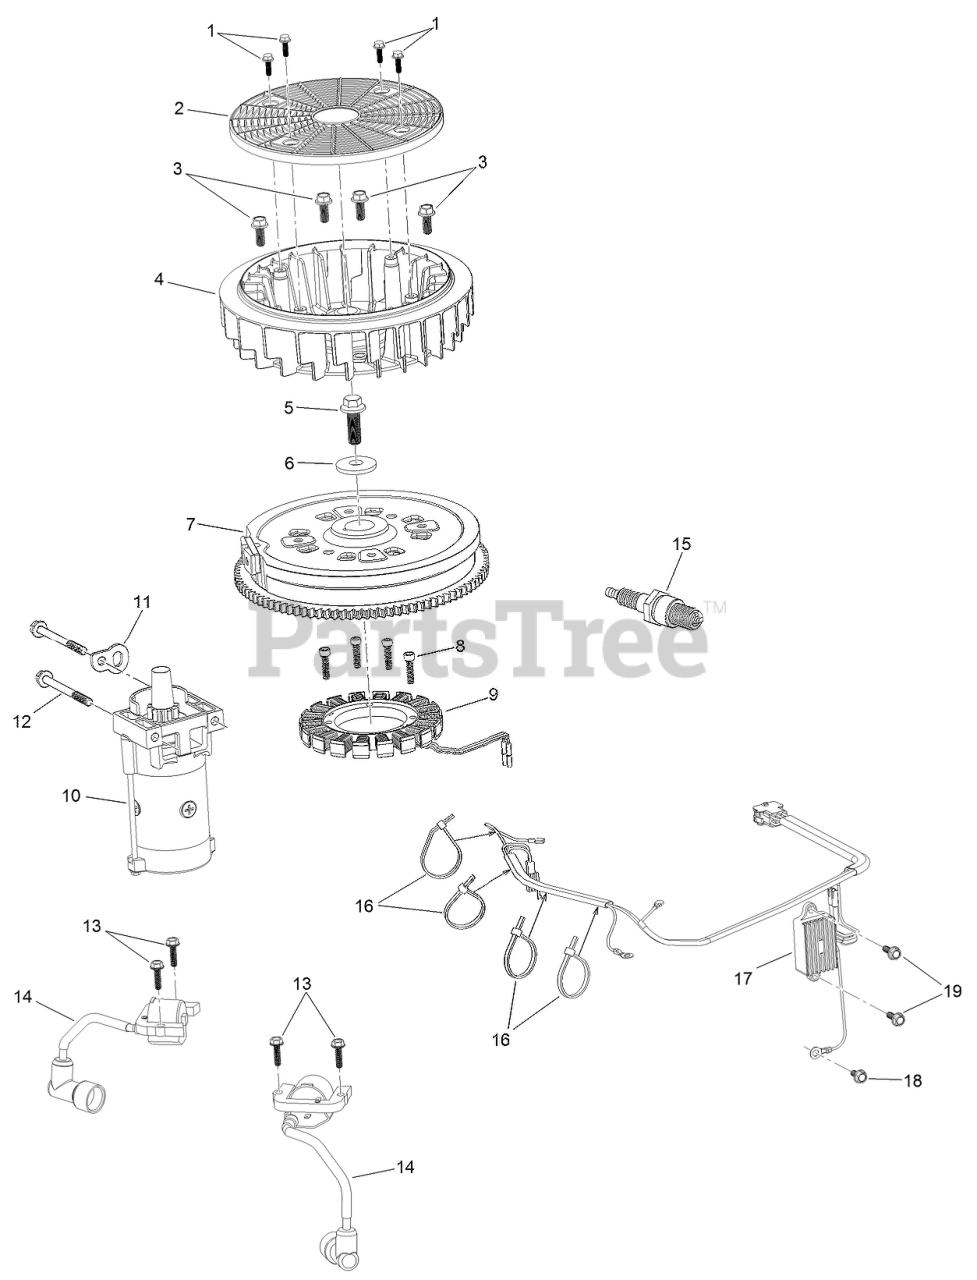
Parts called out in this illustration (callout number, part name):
1	SCREW-HWH
2	SCREEN-ROTATING
3	SCREW-HWH
4	FAN-COOLING
5	SCREW-HWH
6	WASHER-FLAT
7	FLYWHEEL
8	SCREW-HSH
9	ALTERNATOR
10	MOTOR-STARTER
11	BRACKET-LIFT
12	SCREW-HHF
13	BOLT-FLANGE
14	IGNITION COIL ASM
15	SPARK PLUG
16	TIE-ZIP
17	REGULATOR-VOLTAGE W/HARNESS
18	SCREW-HHF
19	SCREW-HHF
